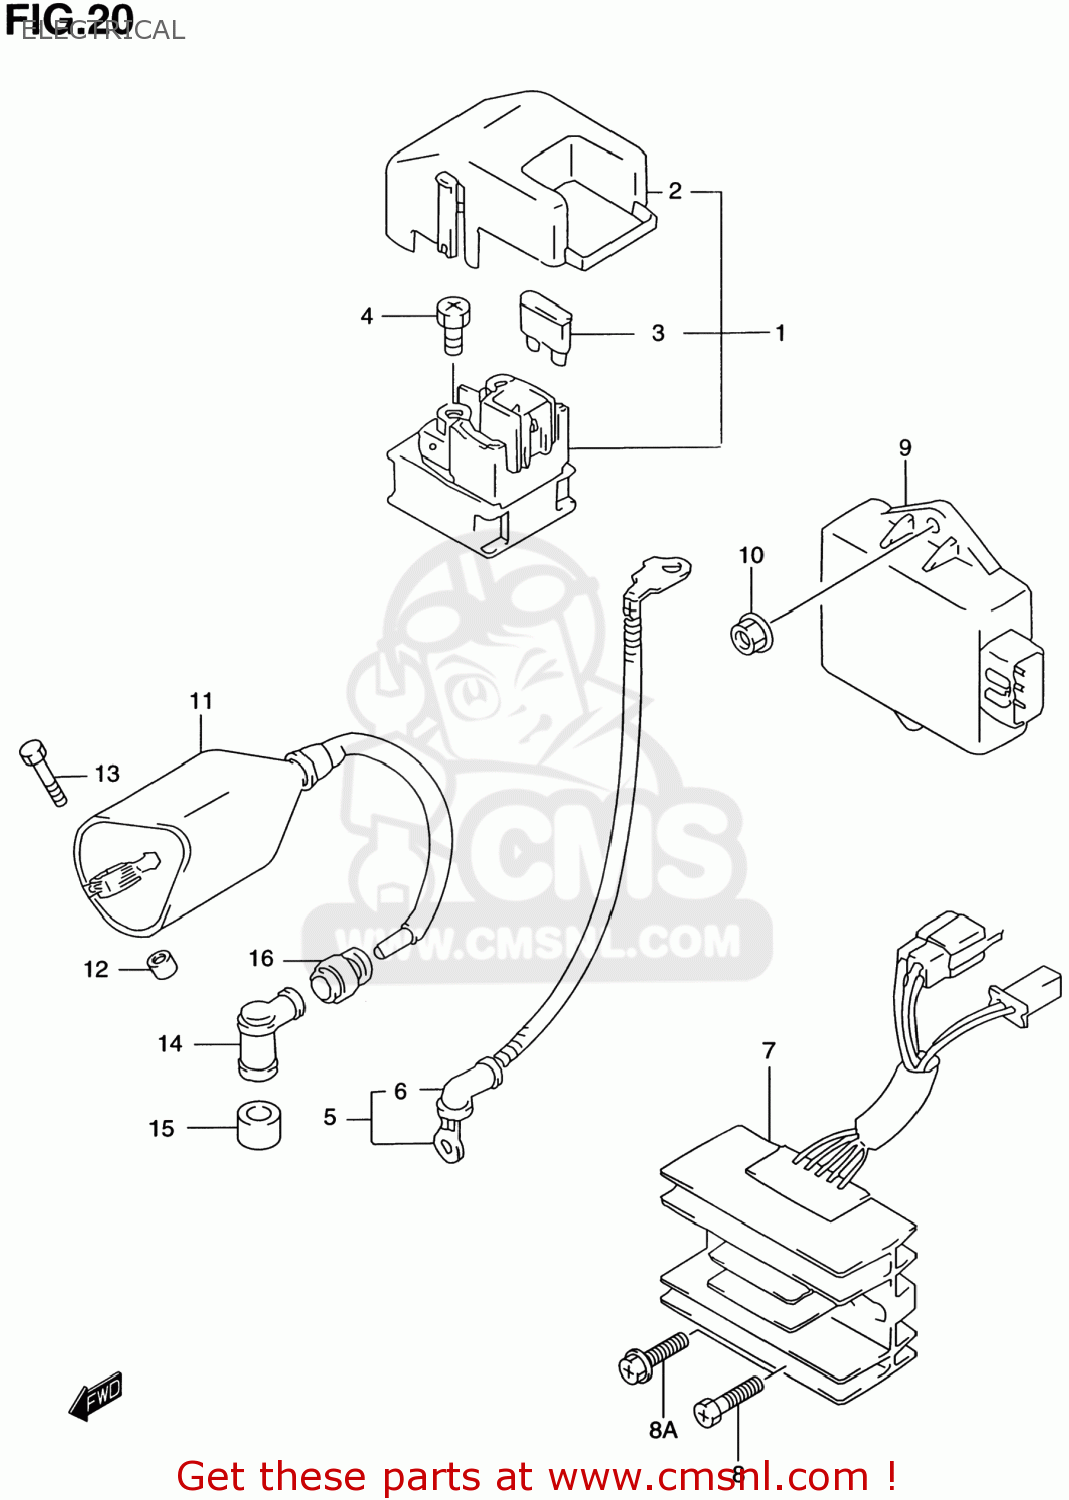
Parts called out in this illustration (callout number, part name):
1	RELAY ASSY,STARTING MOTOR
2	COVER
3	FUSE(20A)
4	SCREW(6X8)
5	WIRE,STARTER MOTOR LEAD
6	CAP,STARTER MOTOR LEAD
7	RECTIFIER ASSY
8	BOLT(6X20)
9	IGNITOR ASSY
10	NUT
11	COIL ASSY,IGNITION
12	SPACER(6.2X12X14)
13	BOLT
14	CAP ASSY,SPARK PLUG
15	SEAL,SPARK PLUG CAP
16	SEAL,HIGH TENSION CORD
